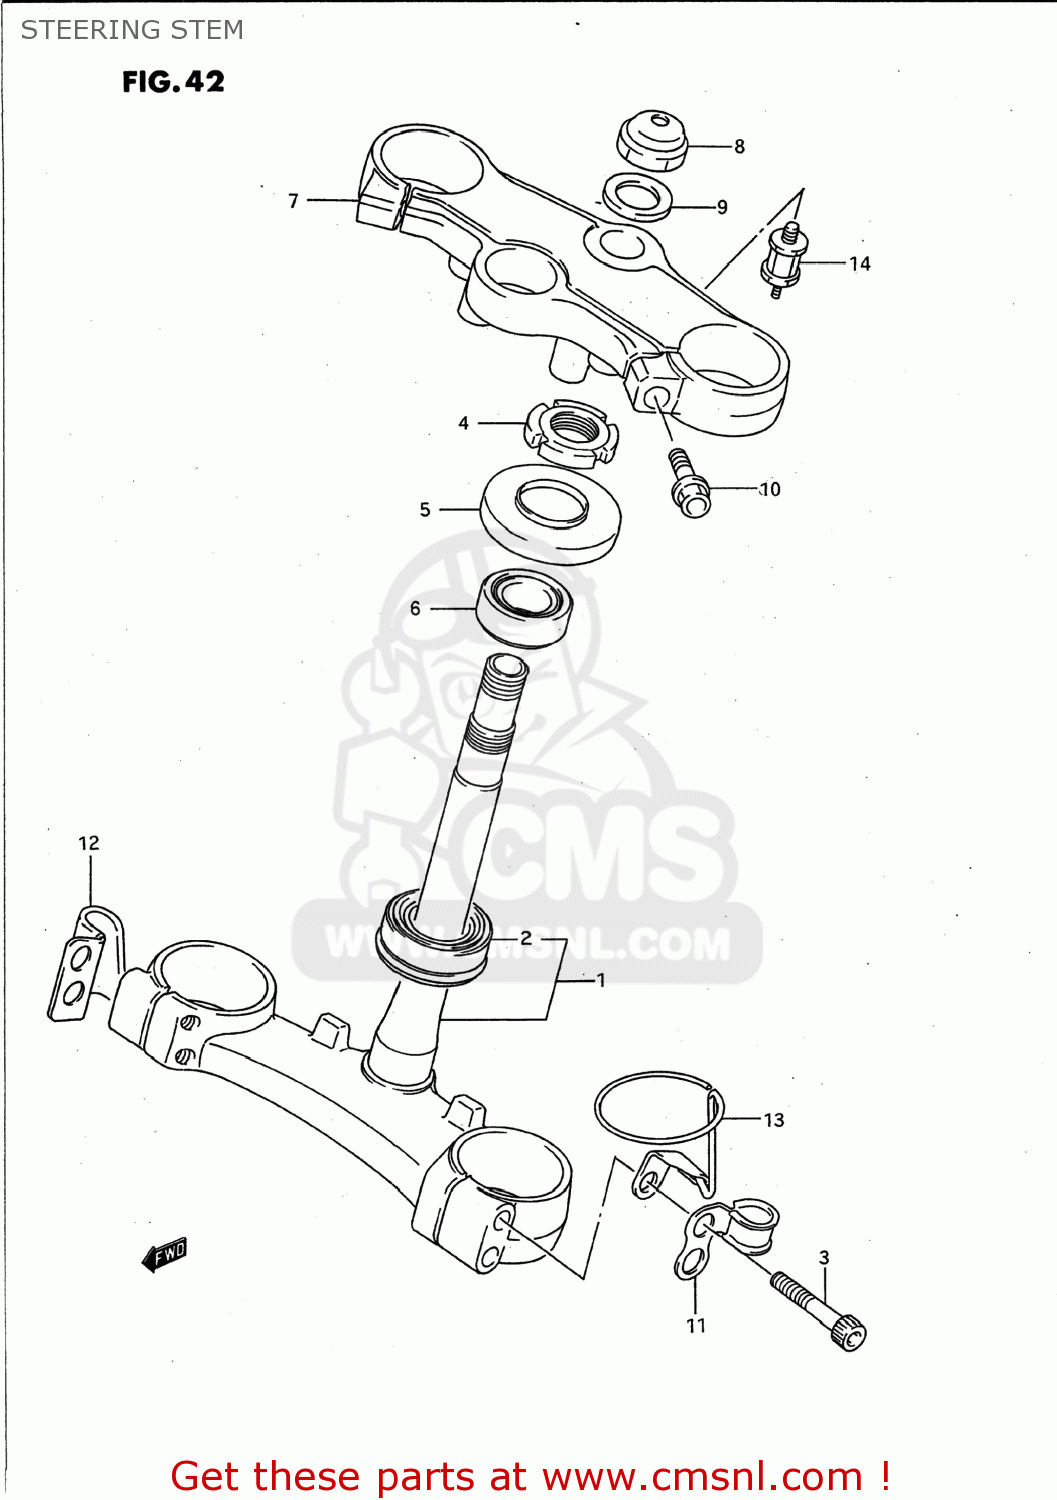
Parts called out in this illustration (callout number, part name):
1	STEM,STEERING
2	BEARING(30X55X17)
3	BOLT
4	NUT,STEERING STEM(25X44X10)
5	SEAL,OIL(34X69X11.9)
6	TAPER,ROLLER BEARING
7	HEAD,STEERING STEM
8	NUT,STEM HEAD
9	WASHER
10	BOLT
11	GUIDE,SPEEDOMETER CABLE
12	CLAMP,CLUTCH CABLE
13	HOLDER,STEERING DAMPER
14	BOLT,SPEEDOMETER CUSHION
